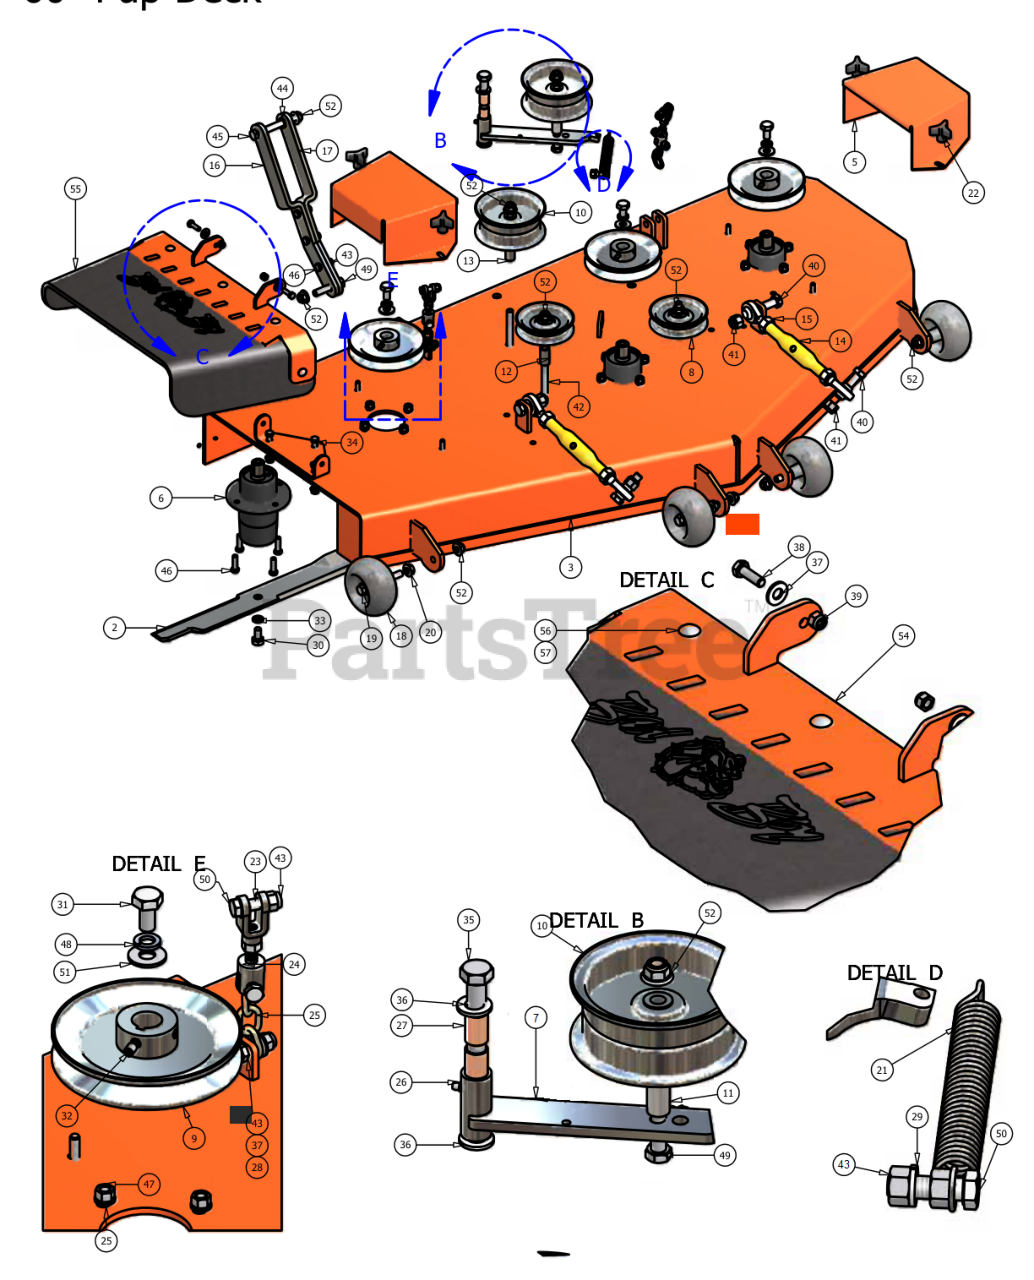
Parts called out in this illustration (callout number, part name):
1	60" Deck Belt
2	60" Fusion Blade
4	Discharge Chute Hanger
5	Pulley Guard
7	Deck Idler Arm
8	4 3/4" Idler Pulley
9	6 1/4" Drive Pulley
10	5 3/4" Flat Idler Pulley
11	1 1/4" Pulley Spacer
12	1 1/2" Pulley Spacer
13	1 3/4" Pulley Spacer
14	Turnbuckle
15	3/4" Left Handed Nut
16	Deck Support Arm (left)
17	Deck Support Arm (Right)
18	Anti-Scalp Rollers
19	1/2" x 4" Bolt (Grade 8)
20	1/2" Flange Nut
21	Deck Idler Spring
22	5/16" Knob
23	Female Yoke
26	Grease Fitting (Drive-In Type)
27	5/8" ID x 1 1/8" Brass Bushing
28	3/8" x 1" Hex Bolt
29	3/8" Lock Washer
30	5/8" x 1.5" Fine Threaded Bolt
31	1/2" x 1 1/2" Bolt (Fine Threaded)
32	3/8" Set Screw
33	5/8" Lock Washer
34	3/8" x 3/4" Hex Bolt
35	5/8" x 4" Hex Bolt
36	.635 ID Plastic Washer
37	.360 ID Plastic Washer
38	5/16" x 1" Hex Bolt
39	5/16" Nylock Nut
40	5/8" x 2 1/2" Hex Bolt
41	5/8" Nylock Nut
42	1/2" x 3 1/2" Bolt
43	3/8" Nylock Nut
44	1/2" Brass Washer
45	1/2" x 4 1/2" Bolt
46	3/8" x 1 1/4" Hex Bolt
47	3/8" Hex Nut
48	1/2" Lock Washer
49	1/2" x 2 1/2" Hex Bolt
50	3/8" x 1 1/2" Hex Bolt
51	1/2" Cupped Washer
52	1/2" Flange Lock Nut
53	2007 Lower Hanger Plate
54	2007 Hanger Plate
55	Rubber Side Discharge
57	5/16" Nylock Flange Nut
